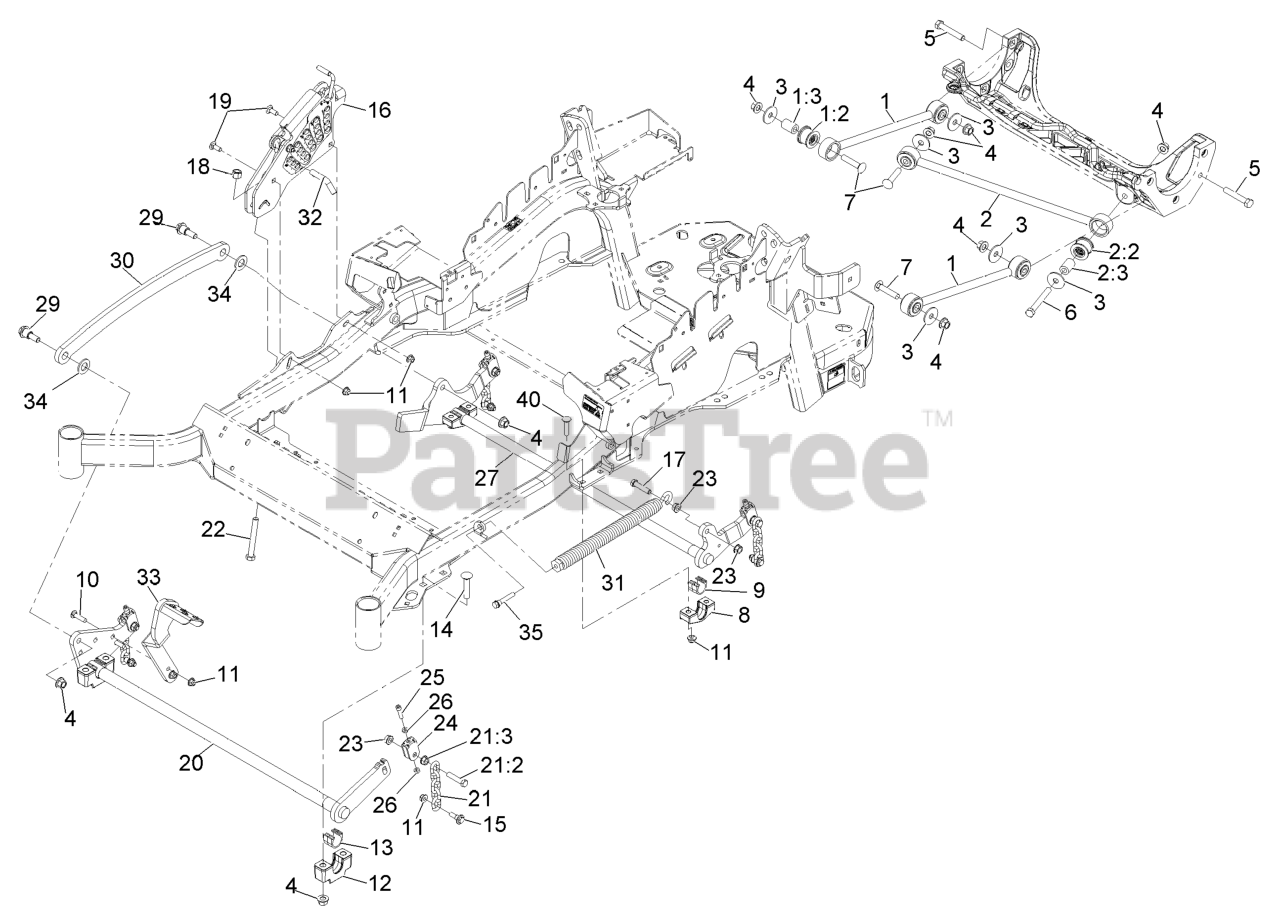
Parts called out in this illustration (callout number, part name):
1	DECK STRUT ASM
1:2	BUSHING-SUSPENSION, RUBBER
2	PANHARD ROD ASM
2:2	BUSHING-SUSPENSION, RUBBER
3	WASHER-THRUST
4	Nut-Lock 1/2-13
5	SCREW-HH
6	SCREW-HH
7	SCREW-CARR
9	BEARING-CROSS SHAFT, REAR
10	SCREW-CARR
11	NUT-HF, NI
12	SUPPORT-CROSS SHAFT, BEARING
13	BEARING-CROSS SHAFT, FRON
14	Bolt-Carriage 1/2-13 X 2 1/2 Spl Neck
15	SCREW-SHOULDER, HHF
16	HOC ASM
17	SCREW-HH
18	NUT-LOCK, NI
19	BOLT-CARR
21	DECK LIFT CHAIN ASM
21:2	SCREW-HH
22	BOLT-TAP
24	YOKE-ADJUST, DECK
25	SCREW-HSH
26	NUT-JAM
27	LIFT-DECK, REAR
29	SCREW-SHOULDER, HHF 1/2-13 X 1.12
30	LINK-LIFT, DECK
31	SPRING-EXTENSION
32	PIN-HOC
33	LEVER-FOOT
34	WASHER-FLAT
35	BOLT-SHOULDER
40	SCREW-CARR
